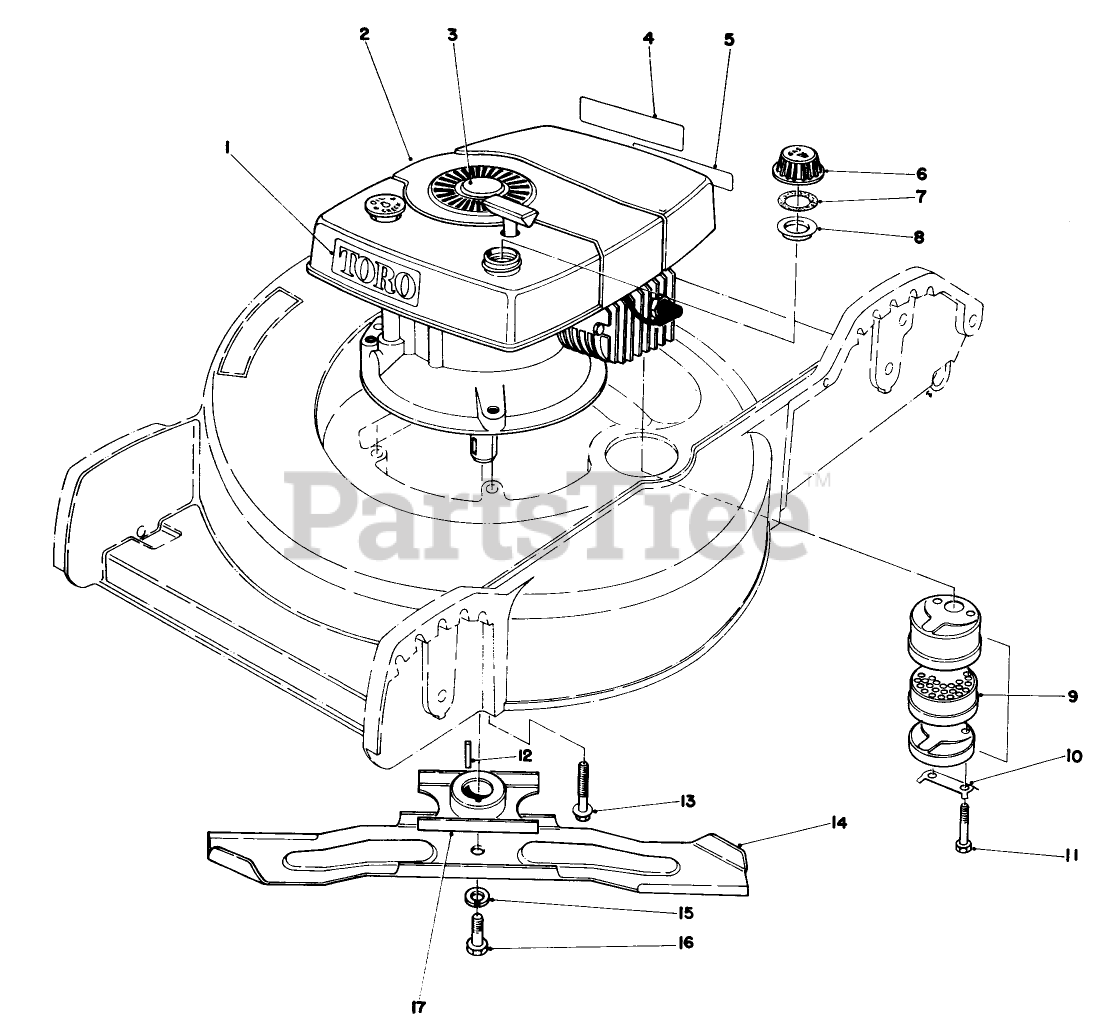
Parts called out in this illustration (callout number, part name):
1	Decal Toro
2	Engine
3	Plug Button
4	Decal Maintenance
5	Decal-Primer Bulb
6	Gas Cap (Incl. Ref. #7 & 8)
7	GASKET
8	GAS CAP BAFFLE
9	Muffer Assy. (Incl. Ref. #10 & 11)
10	CLIP - LOCKING
11	SCREW-HH
12	KEY-SQUARE
13	3/8-16 X 2 CAPSCREW
14	Blade
15	WASHER-LOCK
16	SPECIAL SCREW
17	Blade Retailer
